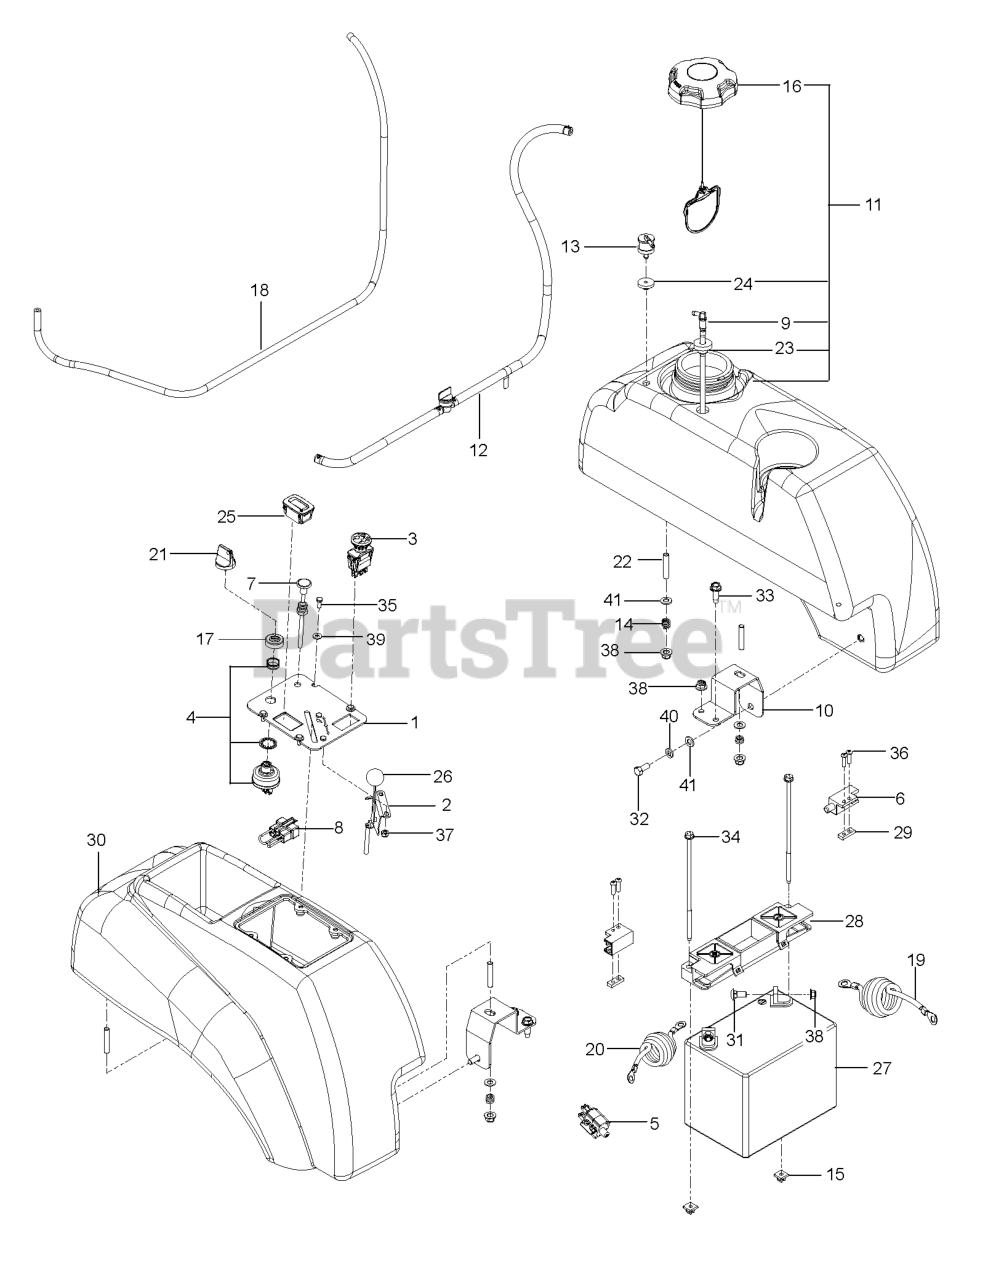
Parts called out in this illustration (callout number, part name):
1	PLATE.CONSOLE.BLACK
2	THROTTLE CONTROL W/BALL KNOB
3	RP SWITCH.PTO.TERMINAL.STD.RED
4	SWITCH, IGNITION, INDAK
5	SWITCH, BRAKE 3P
6	SWITCH, INTERLOCK
7	CABLE, CHOKE
8	PLUG, TIMER
9	FITTING, FUEL
10	SUPPORT, TANK, BLK
11	ASSEMBLY, LT TANK, EPA GRAY
12	FUEL.HOSE.SHUT.OFF.ASM.26".10"
13	VALVE.FUEL.CHECK
15	PUSH NUT-NYLON
16	CAP, FUEL
17	CAP IGNITION NUT
18	HOSE, VAPOR 3/16 X 48"
19	POST.CABLE LONG
20	NEG. CABLE, 28"
21	KEY, IGNITION
22	STUD, 5/16C
23	RUBBER GROMMET
24	GROMMET, CHECK VALVE
25	GUAGE.SRVCMNDR.HRMTR.
26	KNOB.ROUND.BALL.BLACK
27	BATTERY, 12 V 330 AMP
28	BATTERY HOLD DOWN
29	TAPPED PLATE
30	FENDER CONSOLE
31	BOLT 5/16C X 3/4" CARRIAGE
32	HCS 5/16C X 3/4
33	RP BLT 5/16-18 X 1 THRD FORM D
34	BOLT - 1/4-20 X 7.5
35	HCS #10-24 X 1/2
36	SCR #10-24 X .75 SKT HD BLK
37	NUT 10-24 NYLOC
38	5/16-18 NYLOC FLANGE NUT
39	WASHER #10
40	WASHER.LOCK.HVY.HLCL.SPR.5/16
41	FLAT WASHER 5/16 SAE
